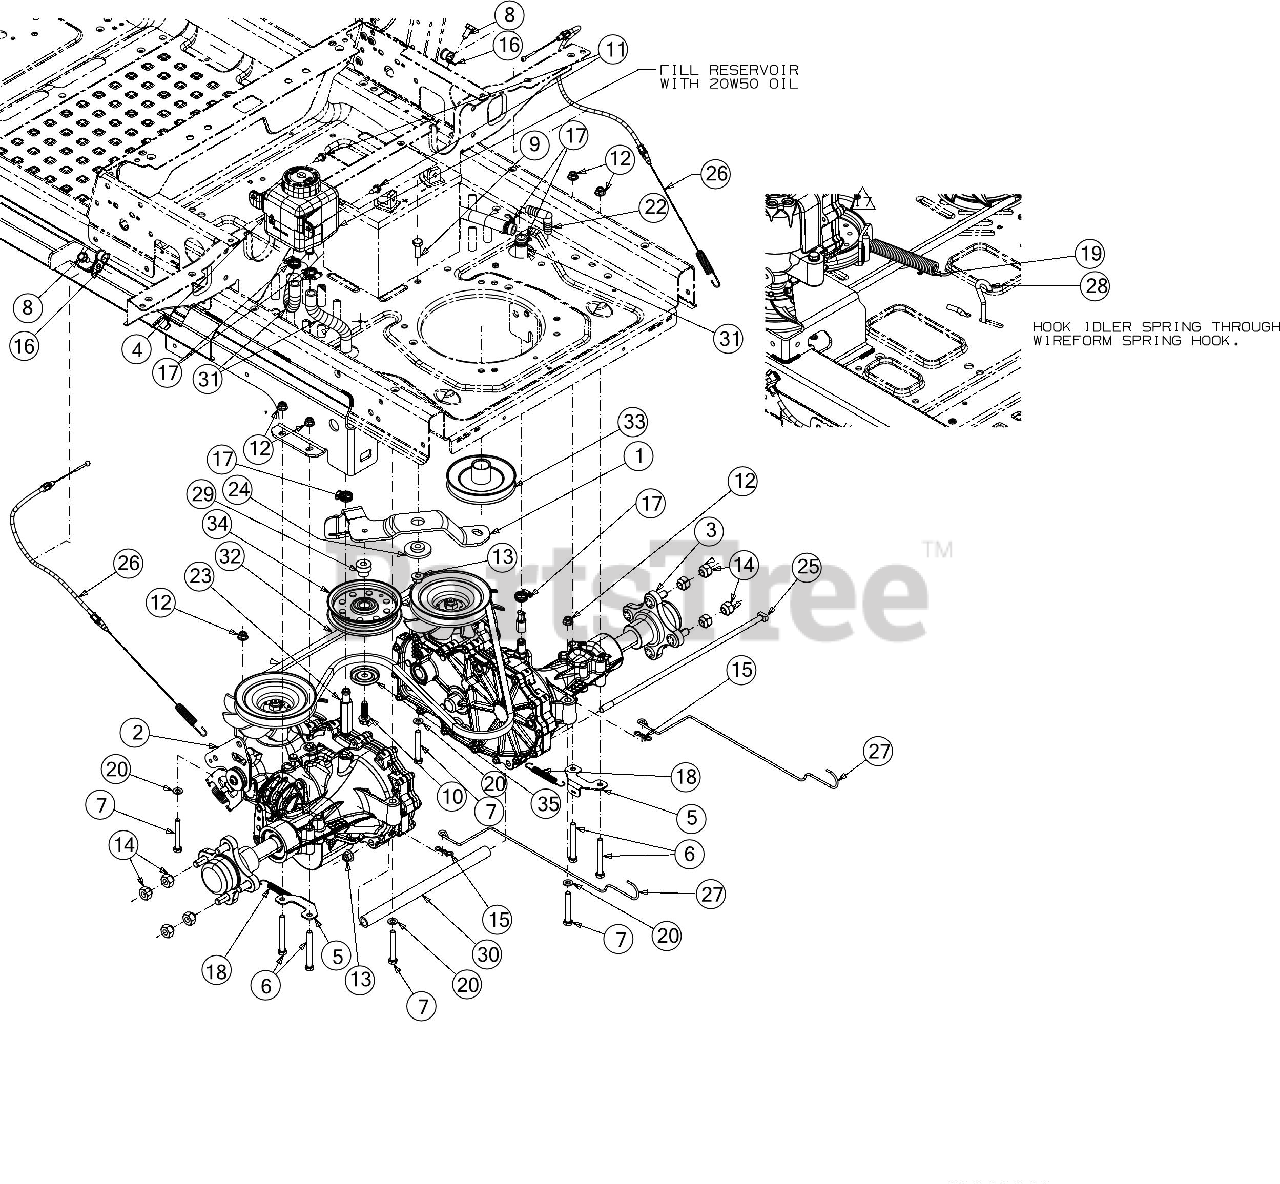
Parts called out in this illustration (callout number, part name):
1	IDLER BRACKET ASSEMBLY
2	HYDRO TRANSMISSION ASSEMBLY (LH)
3	HYDRO TRANSMISSION ASSEMBLY (RH)
4	HYDRAULIC TANK
5	BRAKE RETURN BRACKET
6	HEX SCREW 5/16-18 X 2.75
7	HEX SCREW 5/16-18 X 2.25 GR5
8	SCREW 5/16-18 X .750
9	SCREW 3/8-16 X 1 GR5
10	SCREW 3/8-16 X1.250
11	SCREW 1/4-20X.625
12	FLANGE LOCK NUT 5/16-18
14	LUG NUT 7/16-14
15	BOW TIE COTTER PIN 1/4-5/16
16	CLAMP
17	HOSE CLAMP .75 ID
18	EXTENSION SPRING .38 OD X 3.25 LG
19	EXTENSION SPRING .75 DIA X 5.87
20	FLAT WASHER
22	90 DEGREE NYLON FITTING
23	EXTENSION FITTING 9/16-18
24	SHOULDER SPACER
25	SUPPORT TUBE ROD
26	PARK BRAKE CABLE
27	HYDRO BYPASS ROD
28	IDLER SPRING HOOK
29	SHOULDER SPACER
30	TRANSMISSION SPACER .75OD X 11.31
31	FUEL LINE 1/2 ID"
32	TRANSMISSION DRIVE BELT A X 67
33	TRANSMISSION PULLEY
34	IDLER PULLEY 4.25 DIA
35	IDLER PULLEY CAP
